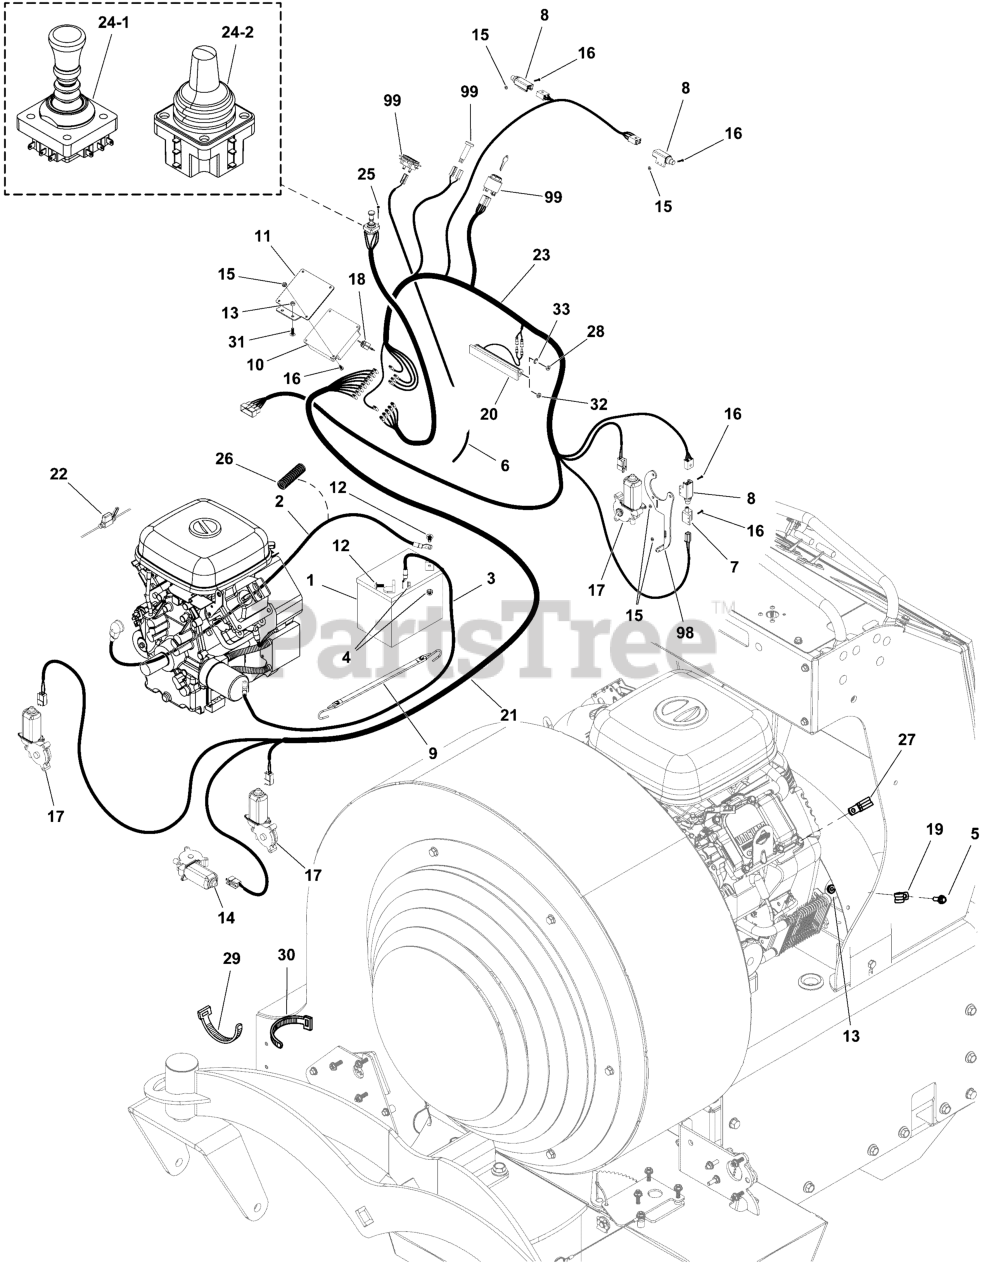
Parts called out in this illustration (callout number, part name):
1	BATTERY
2	BATTERY CABLE, POS, 24.69, 5/16-5/16
3	BATTERY CABLE, NEG, 13.50, 5/16-3/8
4	NUT, 5/16-18 HEX SERRATED FLANGE (SMALL)
5	BOLT, 1/4-20 X 3/4, FLANGE, CZ
6	WIRE HARNESS, TACH X3,Z3
7	SWITCH, PLUNGER, N.C.
8	SWITCH, SAFETY(2P)
9	STRAP, BATTERY
10	KIT, RELAY, CONTROL MODULE
11	BRACKET, RELAY MOUNT - BLK
12	BOLT, 5/16-18 X 3/4, CARRIAGE, GD5, CZ
13	NUT, 1/4-20 HEX SERR. FLANGE
14	MOTOR, DEFELCTOR, LEFT
15	NUT, #10-32, HEX, KEPS, ZC/CL
16	SCREW, #10-32 X 3/4, ALLEN, SS
17	DEFLECTOR, Motor
18	CIRCUIT BREAKER, 15A A-RESET
19	CLAMP, VINYL INSULATED, .50
20	HEADLIGHT ASSY - LED
21	WIRE HARNESS, DEFLECTOR, Z3000 JOYSTICK
22	FUSE HOLDER, Z3000
23	WIRE HARNESS, MAIN, Z3000 JOYSTICK
24-1	KIT, JOYSTICK UPDATE
24-2	JOYSTICK ASSEMBLY, DEBRIS BLOWER
25	SCREW (#10-32 X 3/4, ALLEN, SS)
26	WIRE LOOM, 3/8 ID X 17.5 IN
27	CLAMP, VINYL INSULATED, .75
28	NUT, HEX, M5X.8MM, NYLON INSERT
29	TIE, SELF-LOCKING, 12"
30	TIE, SELF-LOCKING, 6"
31	BOLT,1/4-20X0.750,GR5,STD NECK,SQ,ZC/CL
32	NUT, HEX, M6-1, NYLON INSERT
33	WASHER, 5MM, STAR, CZ
98	Refer to: Parking Brake Group
99	Refer to: Instrument Control Panel Group
